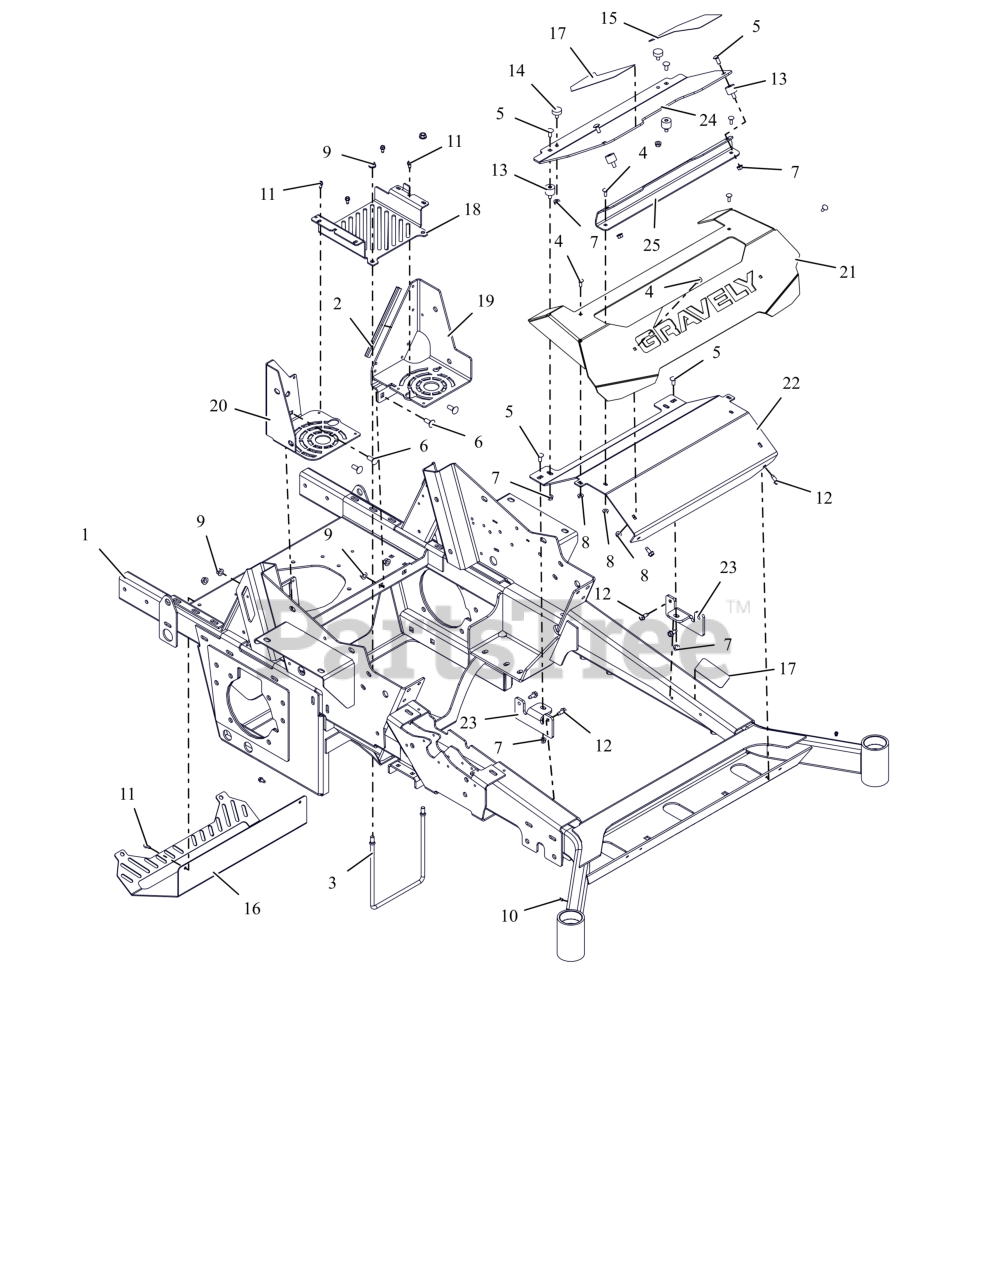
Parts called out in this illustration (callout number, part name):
1	WLDMT, MACH ONE, 72" FRAME (RED)
2	STRIP, COWL
3	ROD, BRAKE MTG
4	BLT, RHSN .25-20X.750 G5 ZCC
5	BLT, RHSSN.31-18X.750 G5 ZCC
6	BLT, RHSN .38-16X1.00 G5 ZCC
7	NUT,SPNLK-FLG .31-18 G5 ZCC
8	NUT-LK-CTR-FLG .25-20 ZC120
9	NUT-LK-CTR-FLG .375-16 GF ZCC
10	FTG, .25-28 FLUSH MNT GREASE
11	SCR-TAP .25-20X.50 HWH ZCC
12	SCR,TAP .312-18X.75 HWH TR ZCC
13	BUMPER,STUD MNTD W/FEMALE INSR
14	BUMPER, RUBBER
15	ANTI-SKID, LH FOOTREST
16	GUARD, MUFFLER (BLACK)
17	ANTI-SKID, FRAME STEP
18	TRAY- BATTERY
19	GUSSET-LH BATTERY TRY/ROPS-RED
20	GUSSET- FAN GUARD/ROPS - RED
21	BMPR-PT300-500 FRT FTRST/ -RED
22	BRKT-FRT BUMPER MTG/BACKER-BLK
23	BRKT, FOOTREST MTG (RED)
24	FOOTREST, PT300-500 (RED)
25	BRKT, FOOTREST SUPPORT (BLK)
